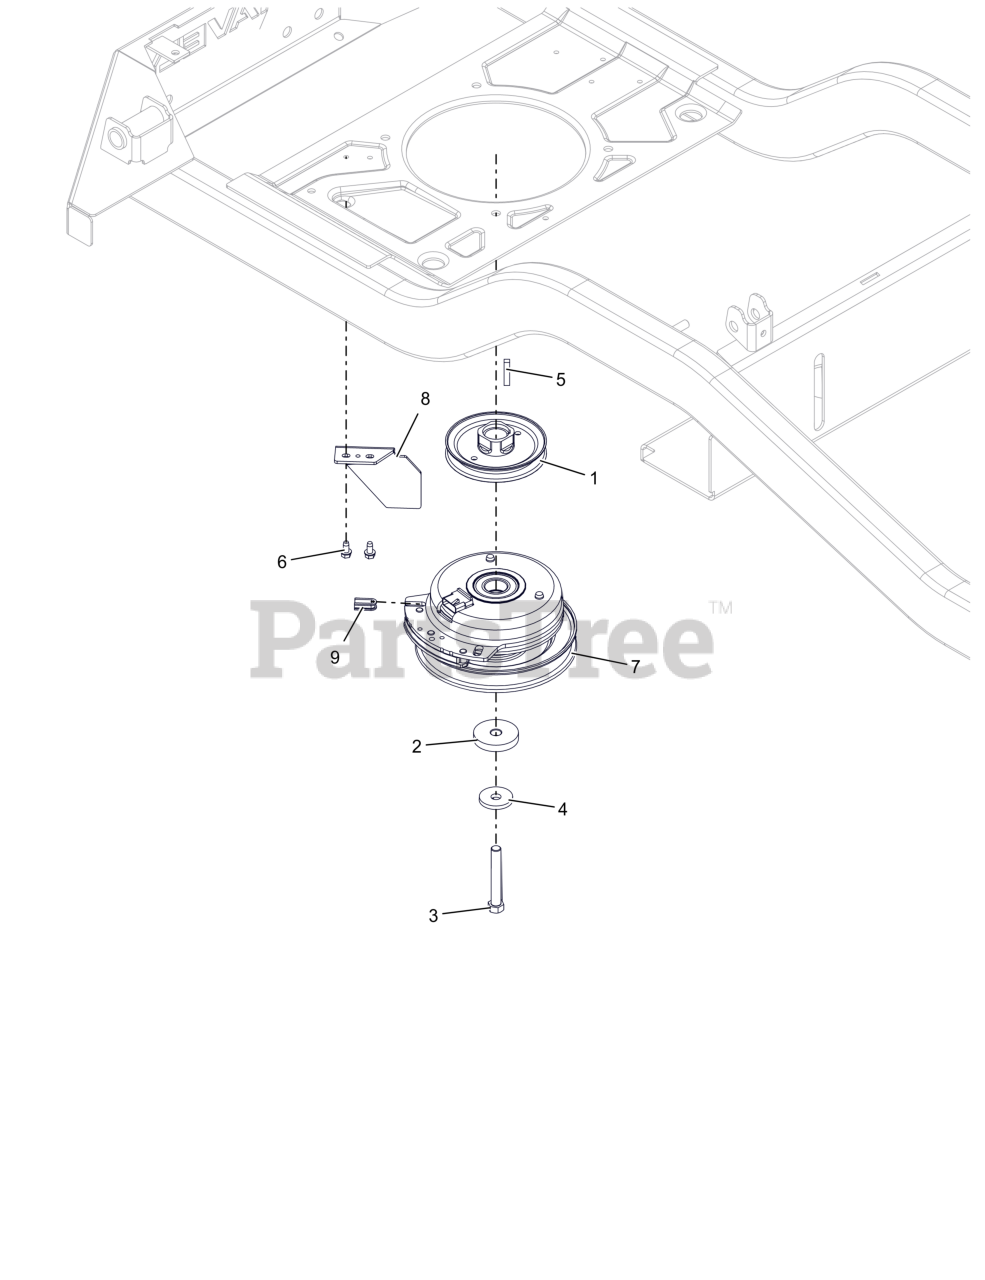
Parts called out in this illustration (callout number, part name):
1	WLDMT-PULLEY-4.50ODX1.003
2	SPACER, .474/.459X2.00X.350
3	BLT, HEX 0.4375-20X3 G8 ZCC NT
4	WASHER, 7/16" SPRING DISK
5	KEY-SQ .25 X 1.25 X .25 SAE
6	SCR-TAP .25-20X.50 HWH ZCC
7	CLUTCH- WARNER 1.00 HD-PTZ
8	BRKT- CLUTCH STOP HD
9	BSHG, CLUTCH
